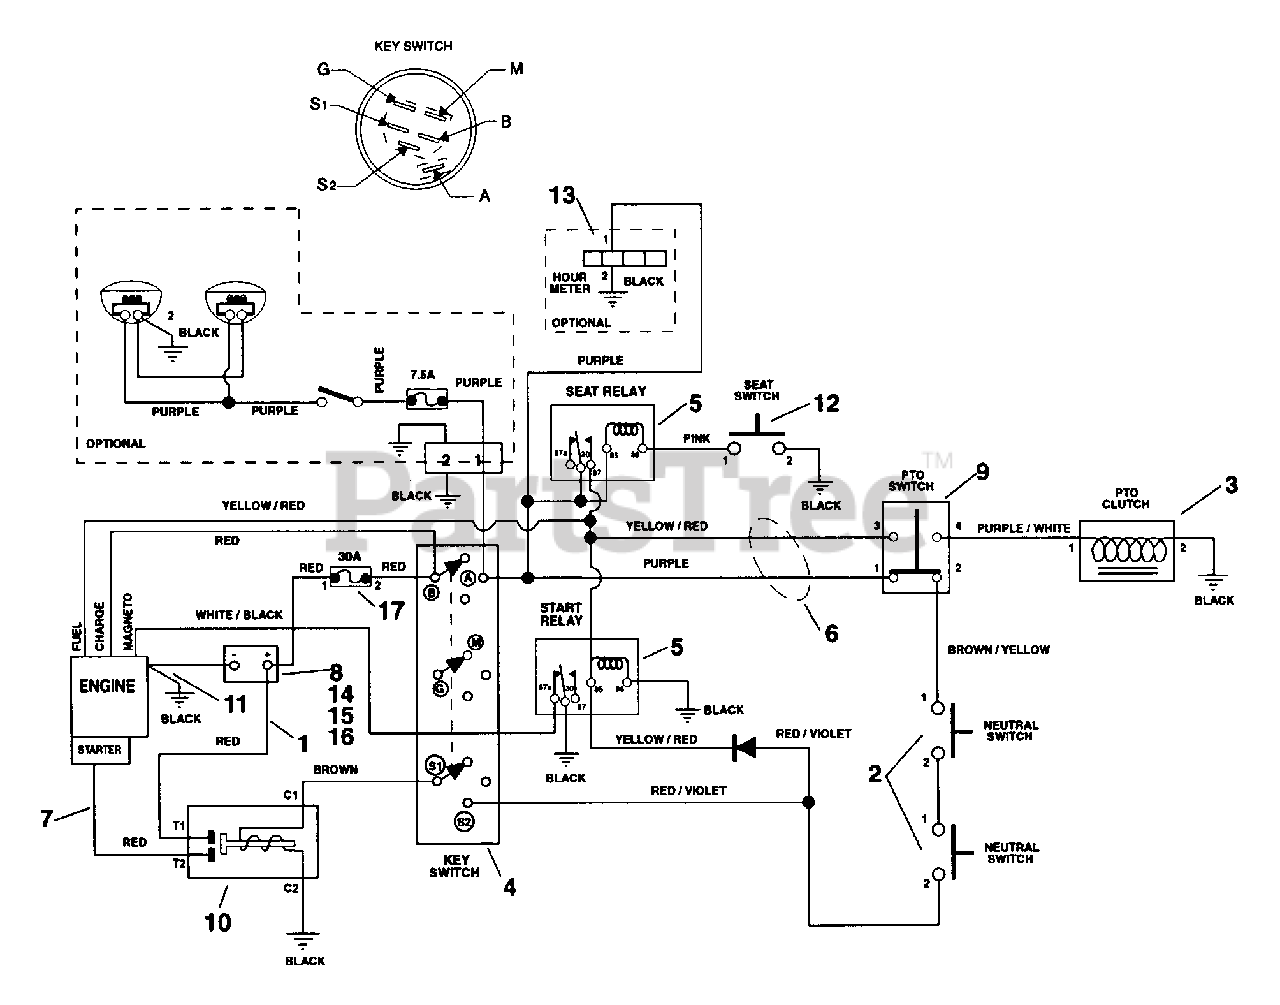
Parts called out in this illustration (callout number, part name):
1	CBL,BATTERY TO SOLENOID
2	SWITCH-NEUTRAL START N.O.
3	CLUTCH, ELECTRIC - WARNER
4	KEY SWITCH
5	RELAY
6	WIRE HARNESS 1648
7	START CABLE 22"
8	BATTERY W/ TUBE
9	SWITCH, CLUTCH WITH RETAINER
10	SOLENOID
11	GROUND CABLE .31X22.00X.31
12	SWITCH- SEAT
13	HOUR METER
14	RUBBER PAD
15	BATTERY STRAP
17	30 AMP Fuse
18	KEY -W/CAP
19	CAP - IGNITION SWITCH
20	NUT- PANEL .562-24 GRECO
21	WSHR-LK-INT .563X.040 PL
22	BOOT, INSULATOR
